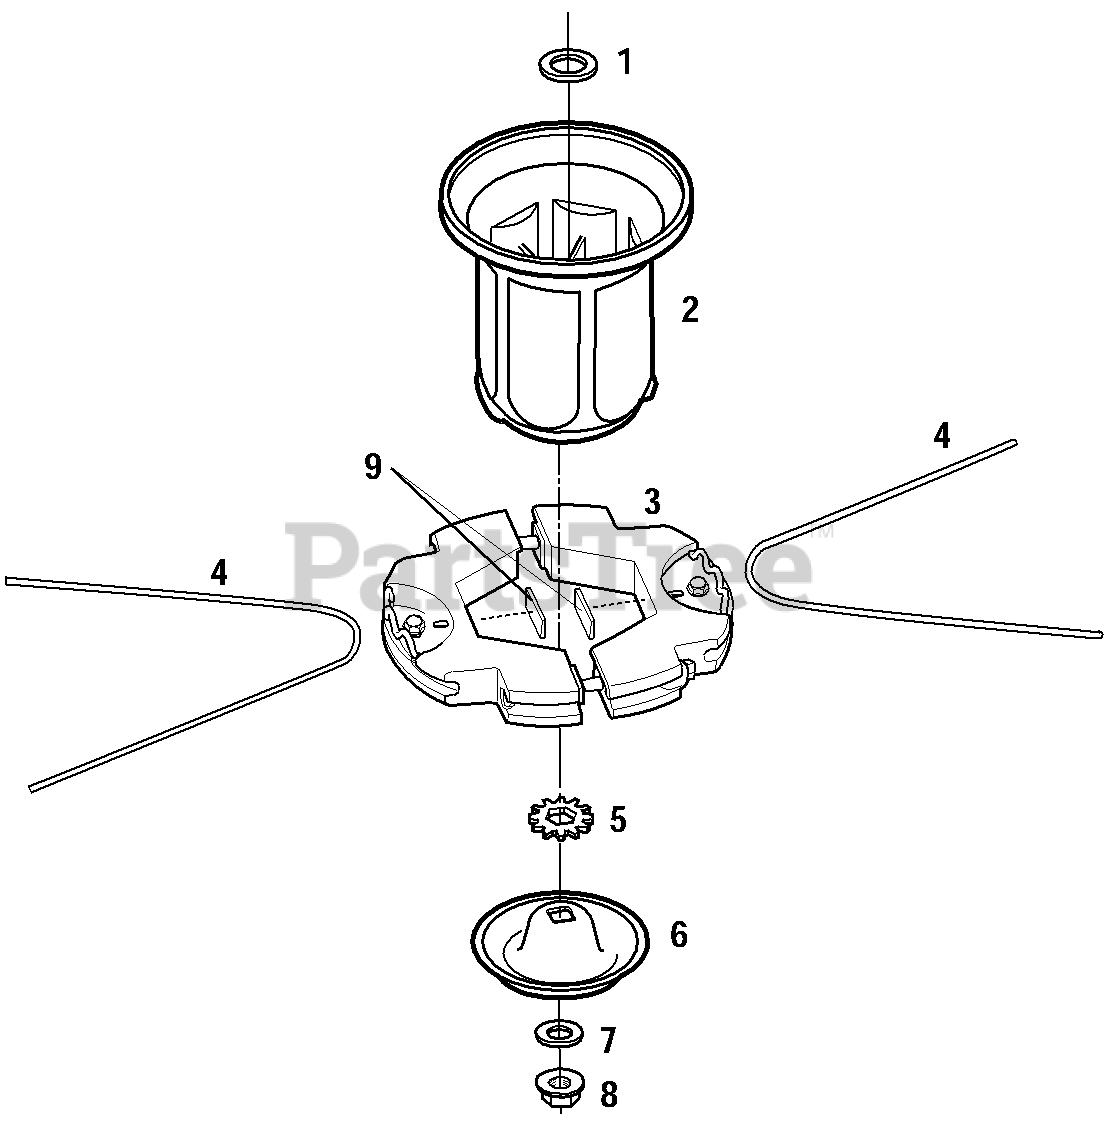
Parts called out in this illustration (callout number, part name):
1	Shoulder Washer
2	Spindle Head
3	Trimmer Head
4	Trimmer String
5	Hex Spline Washer
6	Wear Cup
7	Washer
8	Hex Flange Nut, 1/2-13
9	Rubber Shim Kit (2 shims). Affixed to two inner walls of trimmer head
